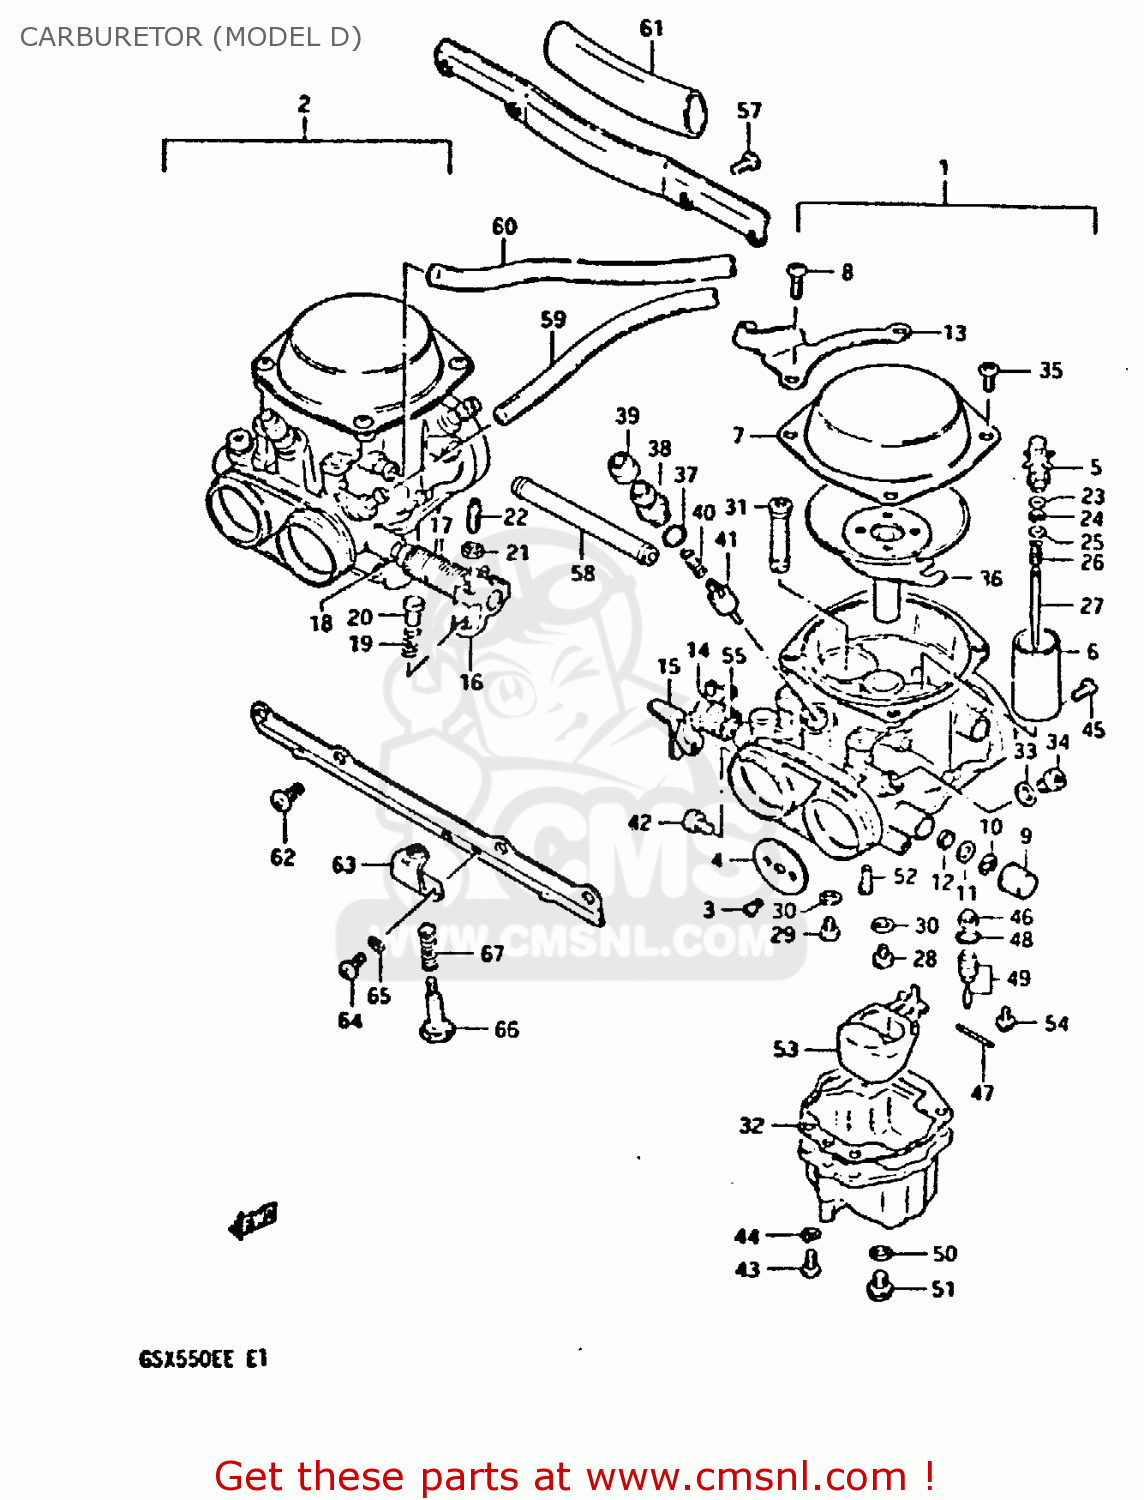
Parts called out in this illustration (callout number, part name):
1	CARBURETOR, LH
2	CARBURETOR, RH
3	SCREW
4	VALVE,THROTTLE
5	HOLDER,GUIDE
6	VALVE,THROTTLE
7	COVER,DIAPHRAGM
8	SCREW
9	CAP,THROTTLE SHAFT
10	E RING
11	GASKET,THROTTLE SHAFT (NAS)
12	SEAL
13	BRACKET,THROTTLE CABLE
14	SPRING,THROTTLE SHAFT
15	SHAFT ASSEMBLY
16	SHAFT ASSEMBLY
17	SPRING
18	RING
19	SPRING,THROTTLE SCREW
20	PIN,THROTTLE LEVER
21	NUT
22	SCREW
23	RING
24	CAP,LEVER
25	WASHER
26	SPRING
27	NEEDLE,JET(5C7-3)
28	JET,MAIN(95)
29	JET,MAIN(102.5)
30	WASHER,NEEDLE NOZZLE
31	JET, NEEDLE (P-2)
32	GASKET,FLOAT CHAMBER (MCA)
33	WASHER
34	SCREW
35	SCREW
36	DIAPHRAGM,CARBURETOR
37	O RING
38	HOLDER,GUIDE
39	CAP
40	SPRING
41	VALVE,STARTER
42	SCREW
43	SCREW
44	LOCK WASHER
45	JET
46	FILTER
47	PIN,FLOAT
48	O-RING,NEEDLE VALVE
49	VALVE ASSEMBLY,NEEDLE
50	GASKET (NAS)
51	PLUG,DRAIN
52	JET(40)
53	FLOAT
54	SCREW
55	RING,THROTTLE SHAFT
56	FLANGE ASSEMBLY,CARBURETOR
57	SCREW
58	PIPE,CARBURETOR
59	HOSE 4.5X8X390
60	HOSE
61	HOSE
62	SCREW
63	BRACKET,SLOW ADJUST
64	SCREW
65	LOCK WASHER
66	ADJUSTER
67	SPRING
